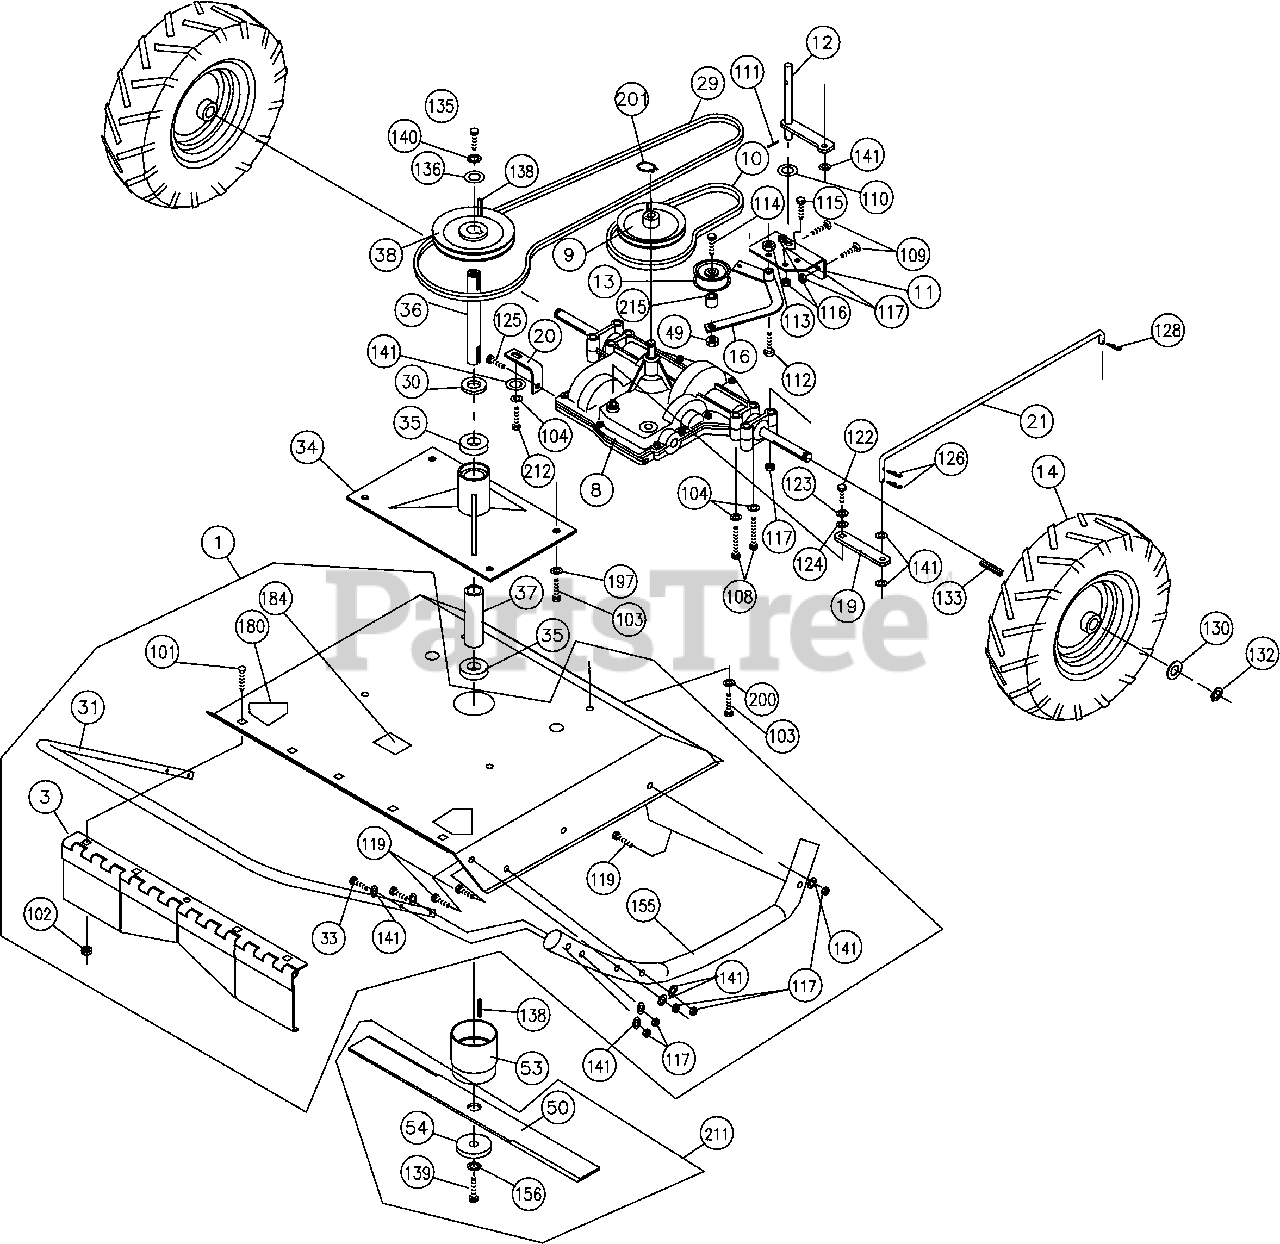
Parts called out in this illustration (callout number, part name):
1	Deck Assembly with Labels
3	Deflector Front BC2402
8	Transaxle 3 SPD BC2402
9	Pulley 5.0" OD ‘A’ Section
10	Belt Traction Drive
11	Plate Pivot Idler/Shifter
12	Shifter Pivot WA
13	Pulley Idler
14	Wheel & Tire 16" SP LH
14	Wheel & Tire 16” SP LH Xtrac No flat BC2403HF and ICF only
16	Arm Idler WA
19	Bar Shift T-axle
20	Angle Support T-axle
21	Rod Link Shifter
29	Belt Blade Drive
30	Spacer Spindle BC2402
31	Bar Guard BC2403
33	Screw Cap 5/16-18 x 1 ¾”
34	Spindle WA BC2402
35	Bearing 7/8" ID Sealed Press
36	Shaft Drive Blade
37	Spacer Spindle Bearing
38	Pulley 7" OD x 7/8" Bore
49	Nut Lock 3/8-16 Thin
50	Blade 24" BC2402
53	Adapter Blade WA
54	Washer Friction Blade
101	Bolt Carriage 1/4-20 x 3/4”
102	Nut Lock 1/4-20
103	Screw Cap 5/16-18 x 1-1/4”
104	Washer Split Lock 5/16”
108	Screw Cap 5/16-18 x 2-3/4 “
109	Bolt Carriage 5/16-18 x 3/4 “
110	Washer Flat 1/2”
111	Pin Cotter 3/32 x 3/4"
112	Bolt Shoulder 1/2 x 1”
113	Nut Lock 3/8-16
114	Bolt Idler
115	Screwcap 5/16"-18 x 2" HCS ZP
116	Nut Jam 5/16-18
117	Nut Lock 5/16-18
119	Screw Cap 5/16-18 x 1-1/2”
122	Screw Cap 1/4-28 x 1/2” GR5
123	Washer lock 1/4” S/T Med
124	Washer 1/4” FC
125	Screw Self Tap 5/16”
126	Pin Hair Cotter
128	Pin Cotter 3/32 x 3/4”
130	Washer 0.765 x 1.250 x 0.060”
132	Ring Snap 0.750”
133	Key 3/16 x 2-1/8”
135	Screw Cap 7/16-20 x 1-1/4” GR8
136	Washer 7/8 SAE
138	Key Sq 3/16 x 5/8”
139	Screw Cap 7/16-20 x 2” GR8
140	Washer Lock 7/16”
141	Washer 5/16 FC
155	Bar Skid BC2403
156	Washer lock 7/16 S/T Med
180	Label OPEI
184	Label Flying Debris
197	Washer Lock 5/16 twisted tooth
200	Washer Lock 5/16 twisted tooth heavy
201	Snap ring
212	Screwcap 5/16”-18 x 3/4”
